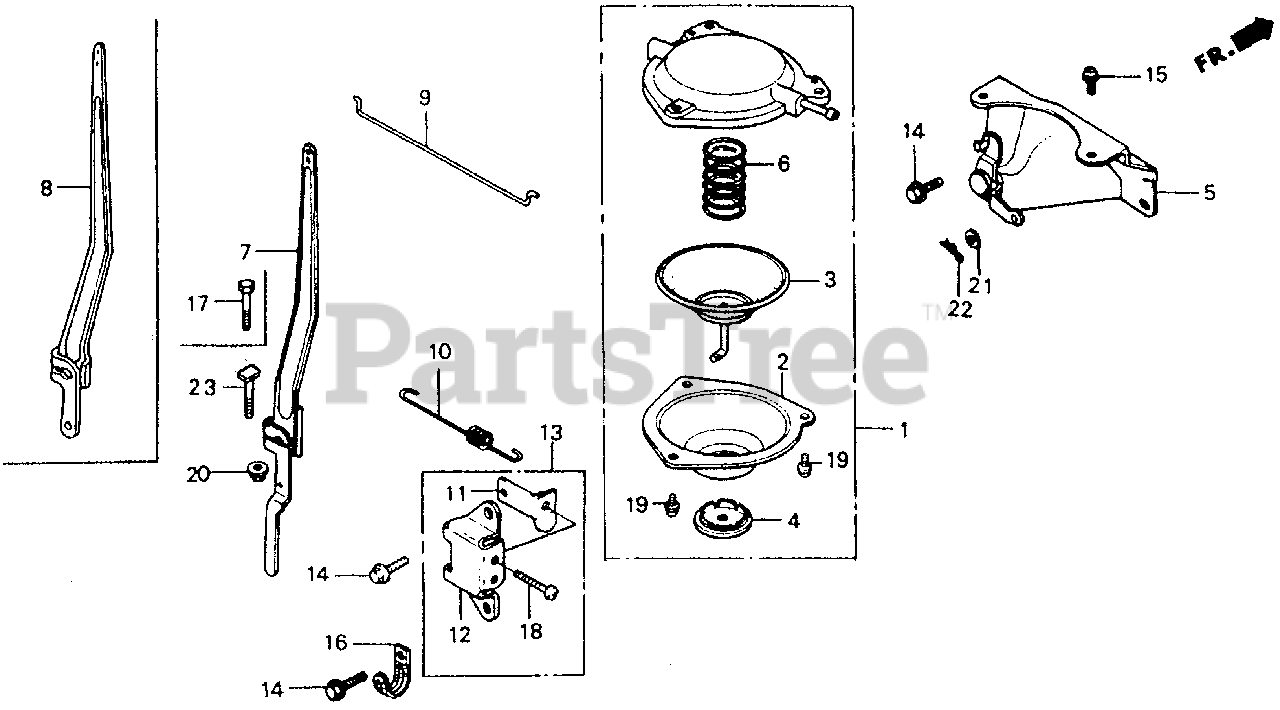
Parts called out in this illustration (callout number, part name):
1	DIAPHRAGM ASSY. (NOT AVAILABLE)
2	COVER, DIAPHRAGM
4	BUSH, DIAPHRAGM COVER
5	STAY, DIAPHRAGM
5	STAY, DIAPHRAGM (NOT AVAILABLE)
6	SPRING, COIL
7	ARM, GOVERNOR
9	ROD, GOVERNOR
10	SPRING, GOVERNOR (NOT AVAILABLE)
11	PLATE, CONTROL
12	BASE, CONTROL
13	LEVER, CONTROL
14	BOLT, FLANGE (6X12) (CT200)
15	SCREW-WASHER (5X8)
16	CLIP (2X50)
17	BOLT, HEX. (6X25)
18	SCREW, PAN (6X28)
19	SCREW-WASHER (4X8)
20	NUT, FLANGE (6MM)
21	WASHER, PLAIN (4MM)
22	PIN, LOCK (4MM)
23	BOLT, GOVERNOR ARM
